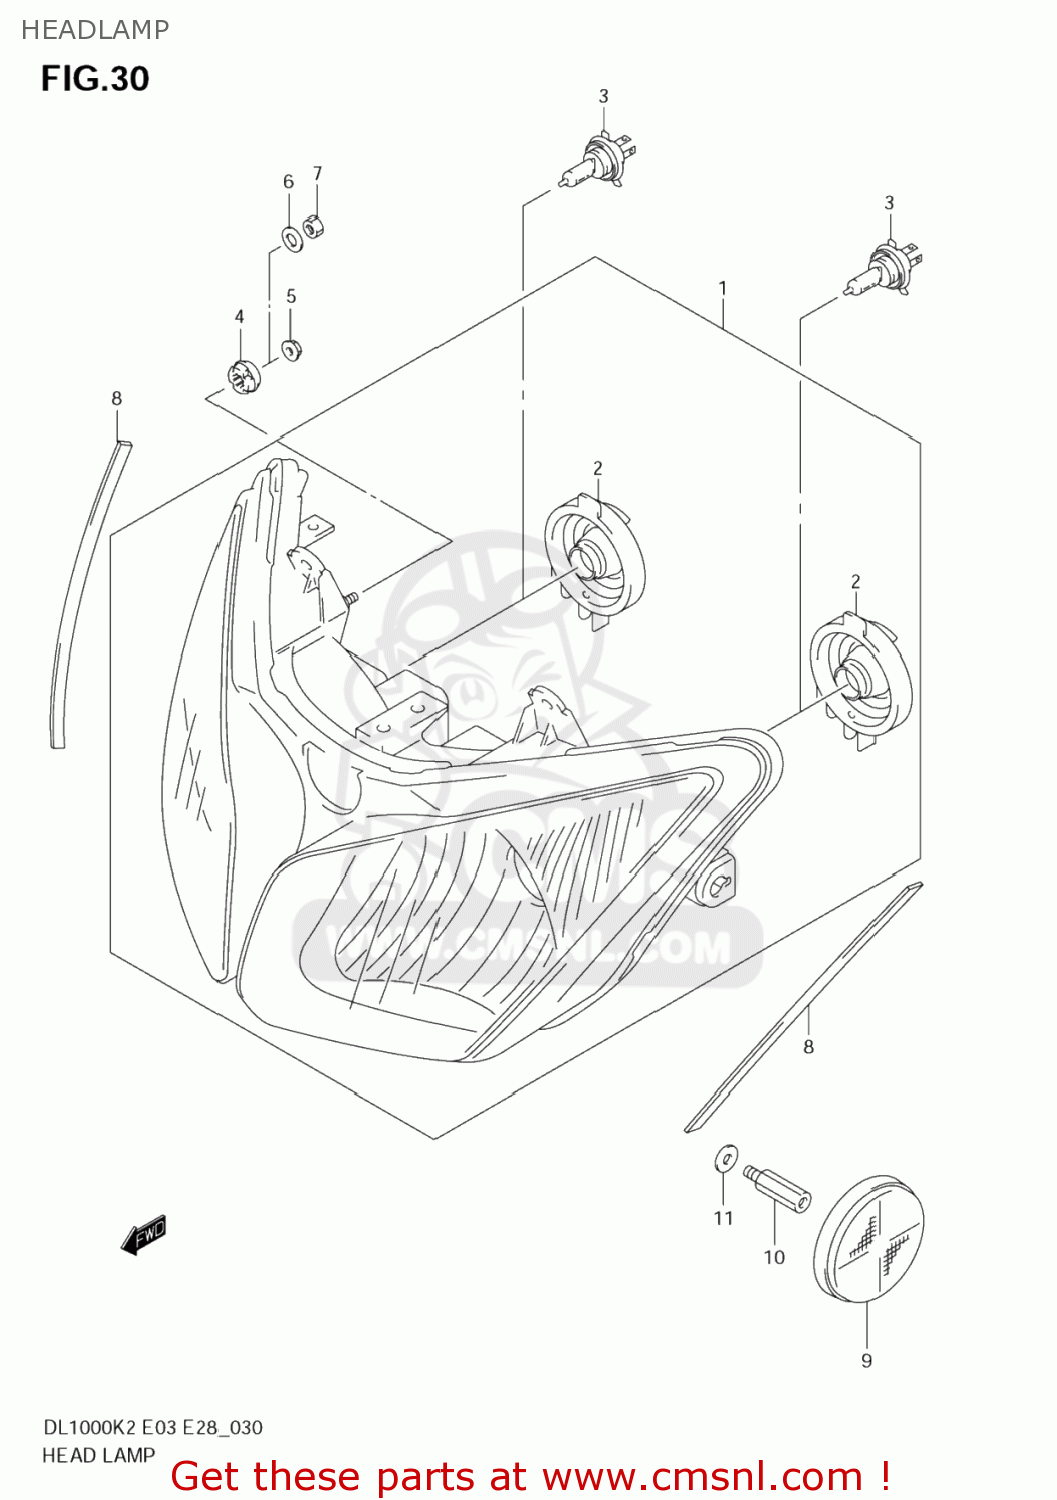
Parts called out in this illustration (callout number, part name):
1	HEADLAMP ASSY
2	COVER,SOCKET
3	BULB(12V60/55W,H4)
4	CUSHION
5	NUT
6	WASHER(6.5X20X1.6)
7	NUT 6MM
8	CUSHION,HEADLAMP
9	REFLECTOR,REFLEX FR
10	BOLT(5X10)
11	WASHER
